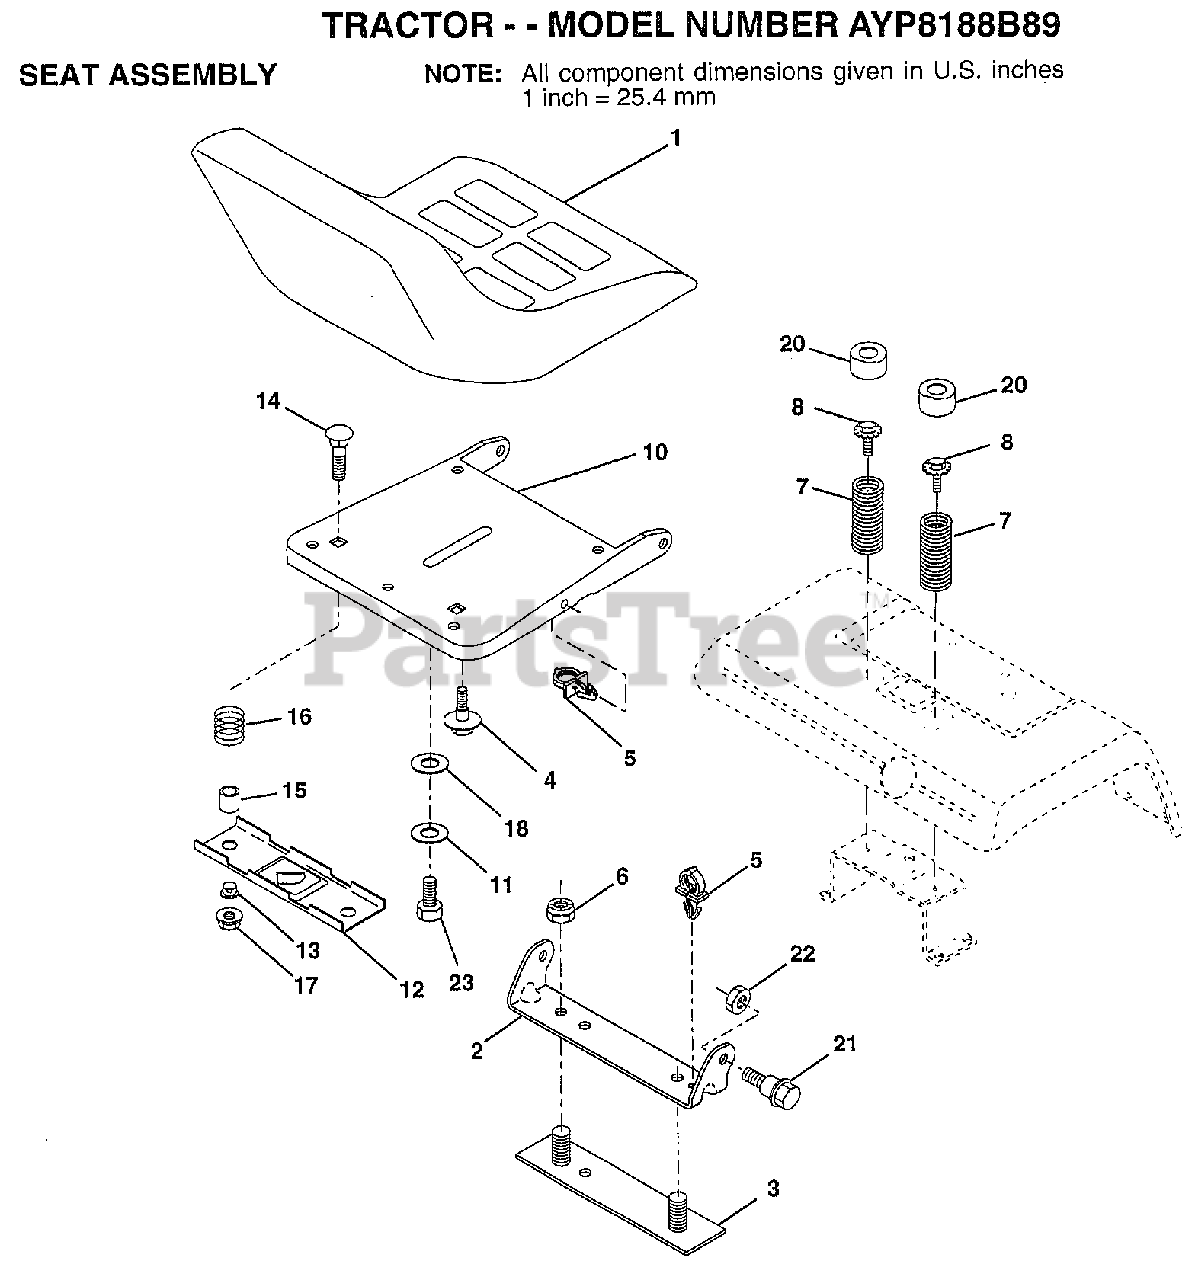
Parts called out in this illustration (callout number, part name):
1	SEAT.2400/1416.BK
2	BRACKET PVT SEAT
3	STRAP ASM FENDER
4	"BOLT,SHOULDER"
5	CLIP.PUSH-IN.HING
7	SPRING COMPRESSIO
8	BOLT.5/16-18.UNC
10	PAN-SEAT
11	LOCKWASHER
12	BRKT SWITCH
13	BUSHING
14	BOLT-RD HD SQ NK
15	SPLIT SPACER
18	WASHER
20	CAP SPRING
21	"BOLT,SHOULDER"
23	BOLT
